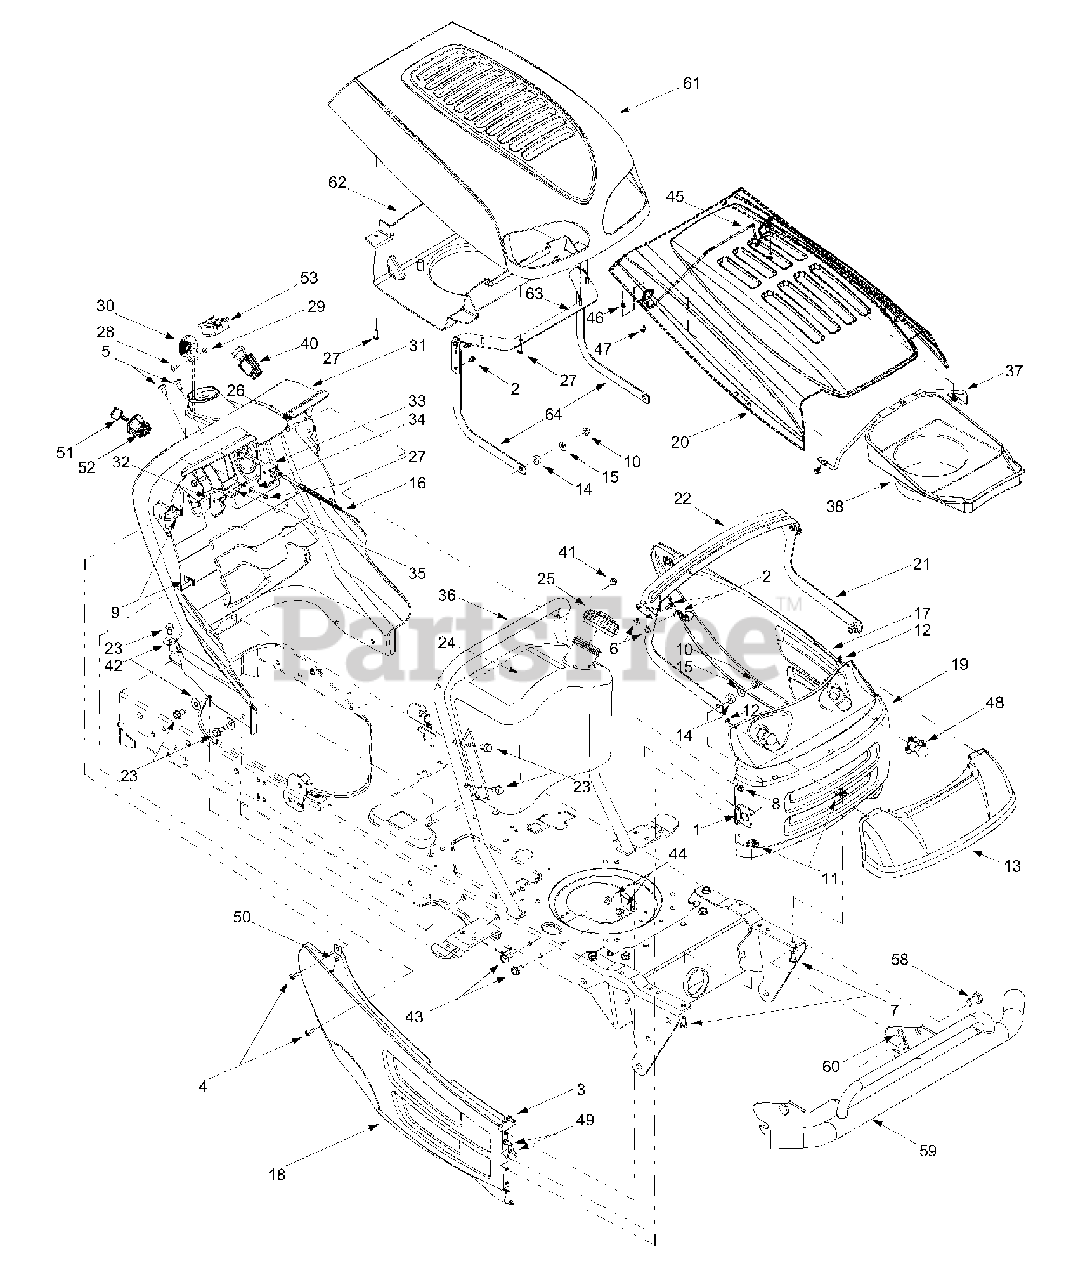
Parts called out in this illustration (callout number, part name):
2	Self-tapping Screw, 1/4-20 x .5
3	Hex Cap Screw, 1/4-20 x .62
4	Phillips Pan Screw, 1/4-20 x .75
5	Truss Phillips Screw, 1/4-20 x .625
6	Screw, #10-16 x .375
7	Hex Cap Screw, 5/16-18 x 1.0
8	Hex Sems Nut, 1/4-20
9	U-type Speed Nut, 1/4-20
10	Flange Lock Nut, 3/8-16
11	U-nut, 5/16-18
12	Retainer Nut, 3/8
13	Headlight Lens (8-style)
14	Rubber Washer, .87 x .33
15	Bell Washer, .401 x .87 x .063
16	Choke Knob/Cable
24	Fuel Tank, Three Gallon
25	Fuel Cap (Fits Either Tank)
26	Self-tapping Screw, 1/4-20 x 1.25
27	Self-tapping Screw, 1/4-15 x .75
28	Truss Phillips Screw, #8-32 x .375
29	Hex Nut, #8-32
30	Throttle Control Knob
31	Dash Panel (Models w/ Electric PTO)
32	Cruise Control Button
33	Parking Brake Button
34	Flat Washer, 9/32 x 1/2 x 1/16
35	Brake/Cruise Pivot Rod
38	Hood Plenum (8-style with B&S OHV V-Twin)
40	Electric PTO Switch
41	Hex Flange Lock Nut, 1/4-20
42	Flat Washer, .349 x 1.0 x .063
43	Screw, 5/16-18 x .875 (Grade 5)
44	Hex Nut, 5/16-18
45	Hood Latch
46	Hex Sems Nut, #10-32
47	Machine Screw, #10-24
48	Headlight Assembly
49	Hex Index Washer Screw, 1/4-14 x .0625
50	Rubber Bumper
51	Ignition Key w/ plastic cover
52	Ignition Switch
53	Systems Indicator Monitor w/ Hour Meter
58	Clevis Pin, .50 x .78
59	Bumper Assembly
60	Internal Cotter Pin
61	Hood, Red (7-Style)
62	Hood Plenum, 7-Style (w/o Intake Bellow)
